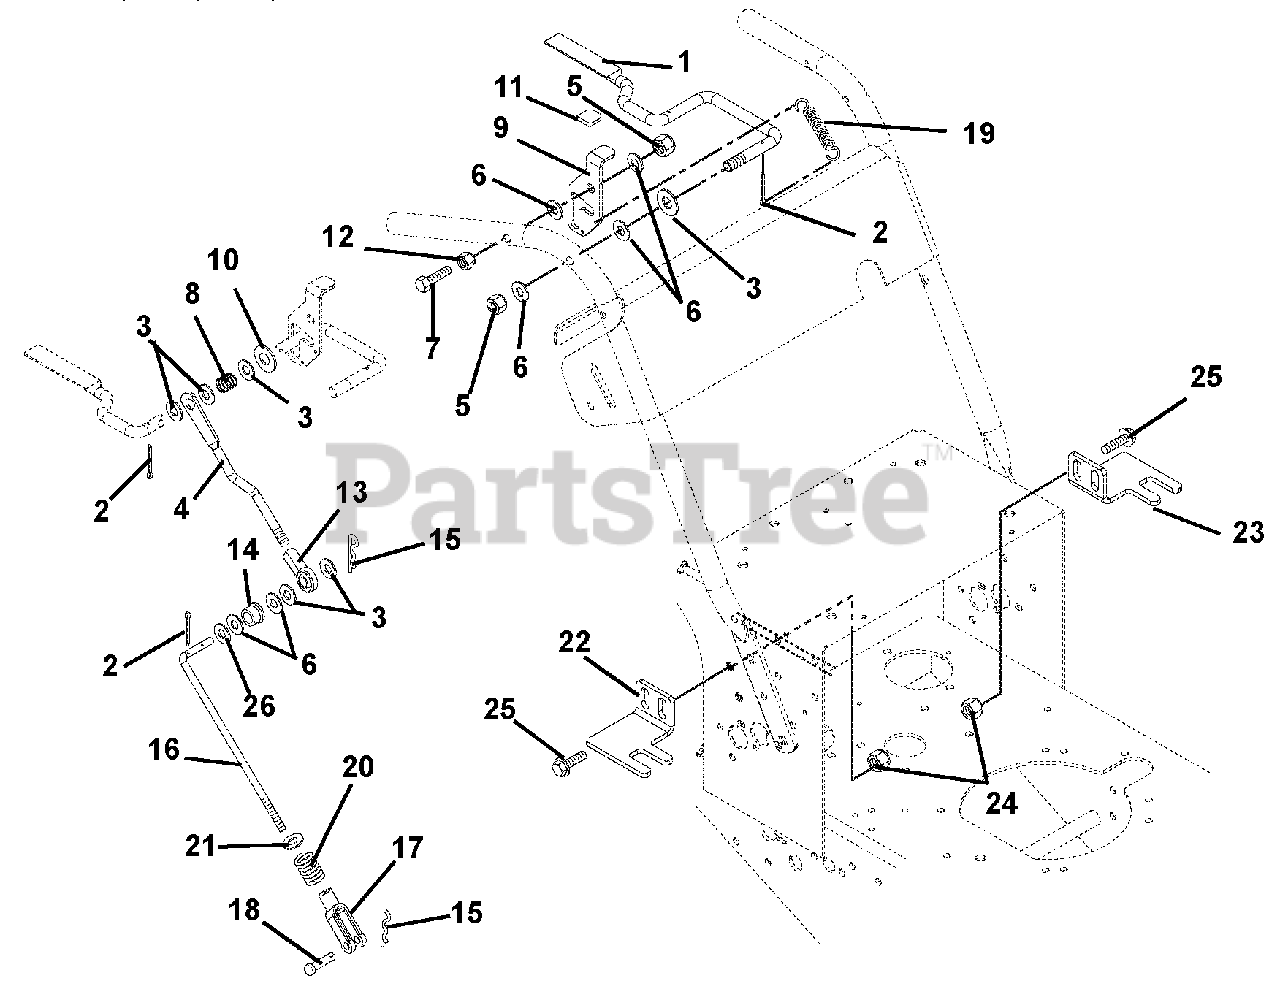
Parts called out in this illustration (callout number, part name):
1	Lever, Hand Control Left Hand
2	Pin, Cotter .09 x .75
3	Washer, Flat-Steel .406 x .812 x .065
4	Rod, Steering Link
5	Nut, Locking-Center .38-16
6	Washer, Flat-Nylon .375 x .75 x .060
7	Bolt, Hex .38-16 x 2.50 Grade 2
8	Spring, Compression .045 x .60 x .75
9	Latch, Right Hand Thumb
10	Washer, Flat-Steel .50 x 1.25 x .083
11	Grip, Thumb Latch
12	Nut, Locking-Jam-Center .375-16
13	Rod End, .38
14	Bushing, Flange .375 x .469 x .25
15	Pin, Hair Internal .08 x .18 x 1.18
16	Rod, Speed Control
17	Clevis, .38-24 Adjustable
18	Pin-Clevis .38 x 1.25
19	Spring, Tension .041 x .50 x 1.75
20	Spring, Compression .093 x .59 x 1.50
21	Washer, Flat-Steel .438 x 1.00 x .083
22	Stop, Hydro Neutral Right Hand
23	Stop, Hydro Neutral Left Hand
24	Nut, Locking-Top-Flange .25-20
25	Bolt, Serrated Hex Flange Washer Head .25-20 x .75
26	Washer, Flat-Nylon .52 x 1.00 x .08
